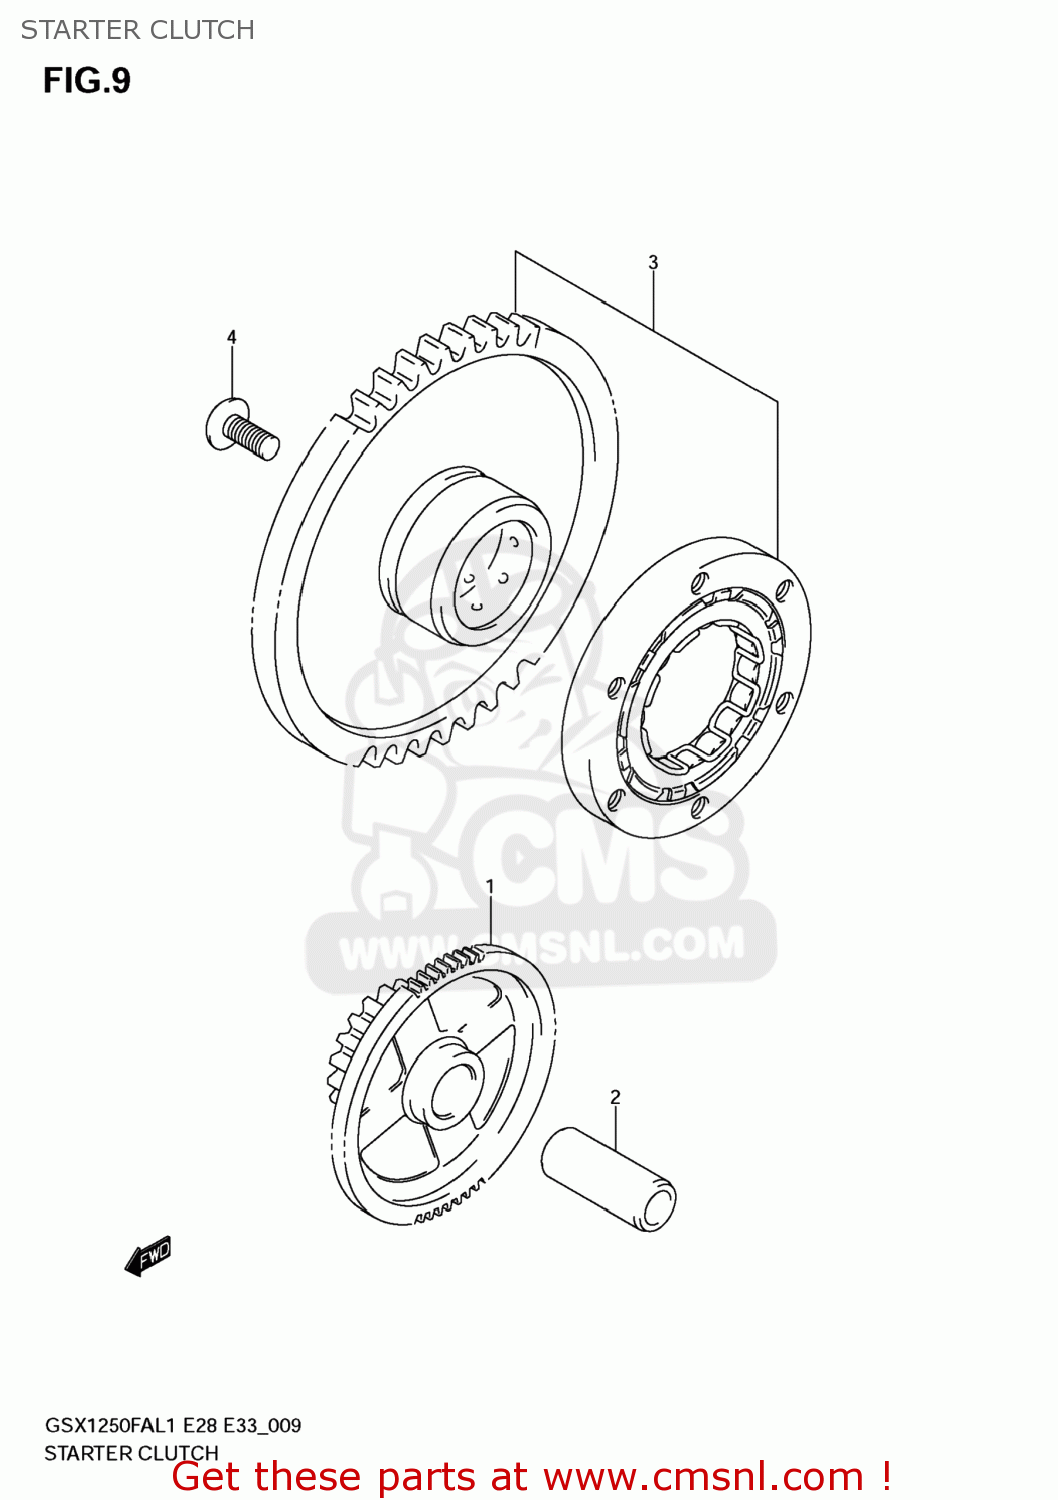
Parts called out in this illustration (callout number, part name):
1	GEAR,STARTER IDLE(NT:12,53)
2	PIN(7X11X42)
3	CLUTCH SET,STARTER
4	SCREW(8X16)
